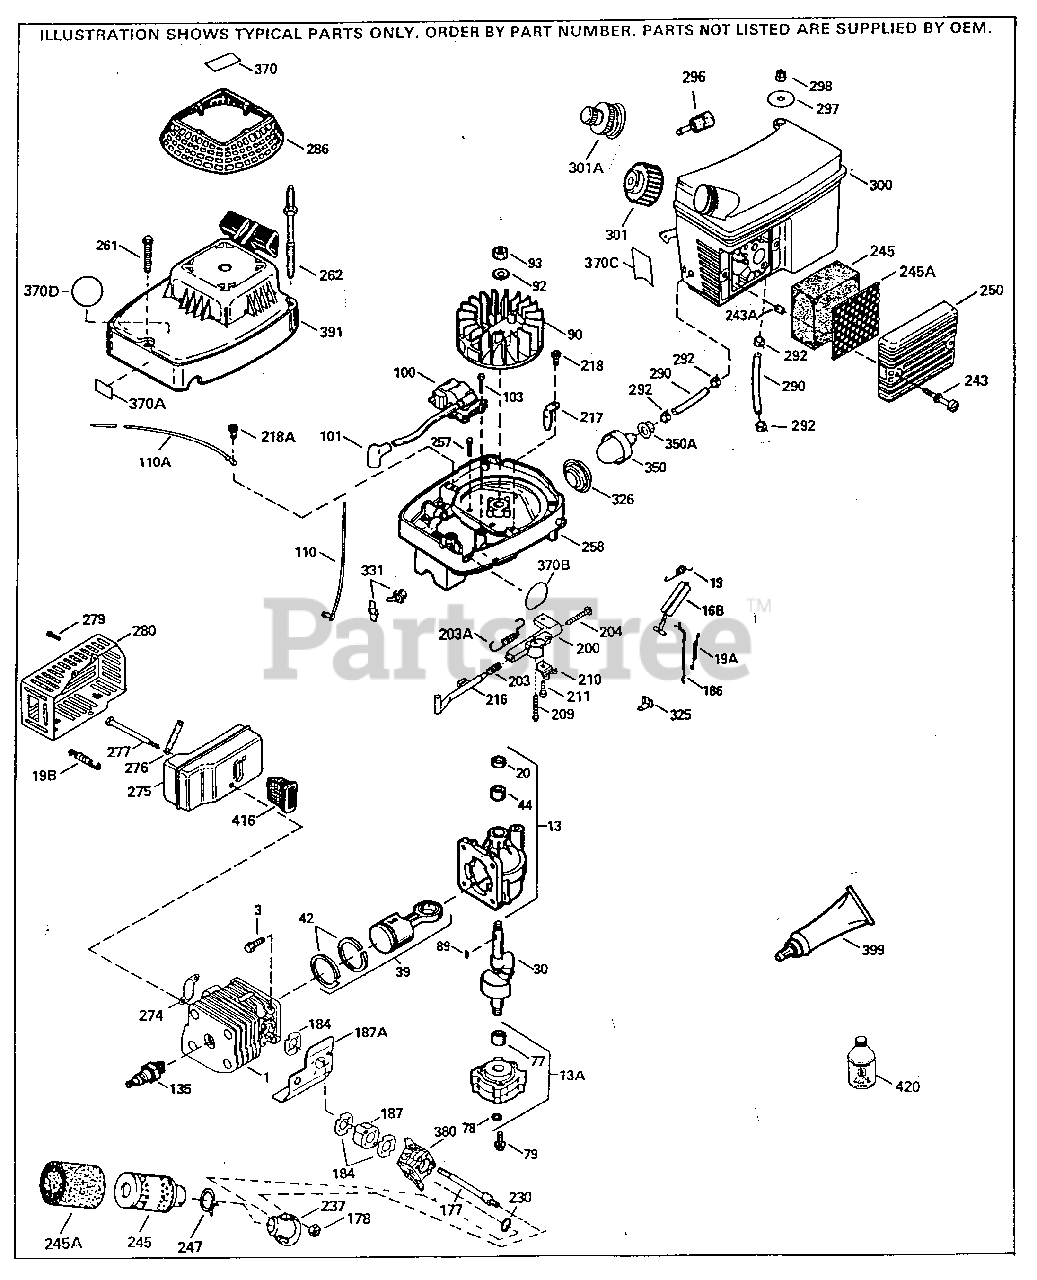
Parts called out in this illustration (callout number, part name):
1	"Cylinder
3	Screw, Torx T-30, 1/4-20 x 43/64"
13	Crankcase Ass'y. (Incl. 20 & 44)
13A	Crankcase Cover Ass'y. Incl. 77 & 78
16B	Air Vane
19	Governor Spring
19A	Backlash Spring
19B	Heat Shield Spring
20	Oil Seal
30	Crankshaft
39	Piston & Rod Ass'y. (Incl. 42)
42	Ring Set
44	Cartridge Bearing
77	Cartridge Bearing
78	Oil Seal
79	Screw, 1/4-20 x 3/4"
89	Flywheel Key
90	Flywheel (Reverse fin)
92	Belleville Washer
93	Flywheel Nut, 3/8-24
100	Solid State Ignition (Incl. 101)
101	Spark Plug Cover
103	Screw, Torx T-15, 10-24 x 1"
110	Ground Wire
110A	Ground Wire
135	Resistor Spark Plug (RCJ6Y)
177	Carburetor Mounting Stud
178	Lock Nut, 10-24
184	Carburetor Gasket
186	Governor Link
187A	Air Baffle
200	Speed Control Body
203A	Control Bracket Spring
204	Screw, 8-32 x 1"
211	Screw, 10-32 x 1/4"
216	R.P.M. Adjusting Lever
218A	Screw, 8-32 x 1/2"
230	"O" Ring
243	Screw, 10-32 x 29/32"
243A	Thread Insert
245	Air Filter (Poly) (also available in Packaged Part #740097 (incl. 450255 & 450257))
250	Air Cleaner Cover
257	Screw, 10-24 x 1/2"
258	Blower Housing Base
261	Screw, 8-32 x 1-9/16"
274	Exhaust Gasket
275	Muffler (Incl. 274 & 277)
276	Locking Plate
277	Screw, 1/4-20 x 2.469"
286	Starter Screen
290	Fuel Line
292	Fuel Line Clamp
298	Nut, 8-32
300	Fuel Tank & Primer Ass'y. Incl. 290, 292, 298, 301, 350, 350A & 370C
301	Fuel Cap
325	Control Spring Clip
326	Blower Housing Plug
350	Primer Ass'y.
370B	Plug Decal
370C	Primer Decal
370D	Fuel Mix Decal
380	Carburetor (Incl. 184) (Refer to Divi sion 5, Section A, page A12-2 or Fich e 24, Grid F-3 for breakdown
391	Rewind Starter & Housing Ass'y. Refer to Division 5, Section C, page 33 or Fiche 24, Grid G-1 for breakdown
399	Gasket Eliminator (Loctite 515) As re quired
420	2-Cycle Oil with Fuel Stabilizer - 8 oz.
